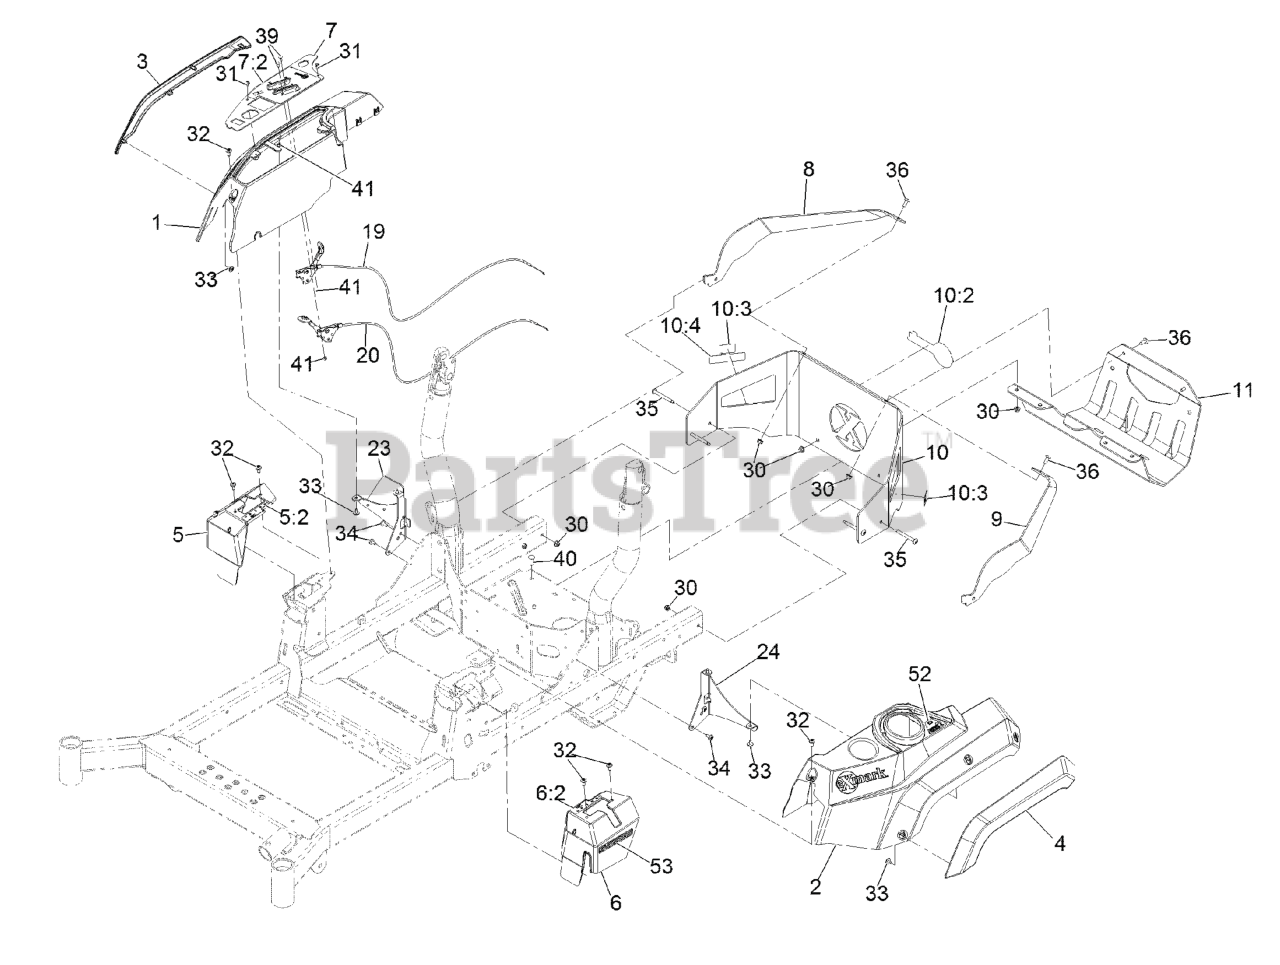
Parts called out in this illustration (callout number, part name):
1	CONSOLE-EXMARK, RH
2	CONSOLE, LH
3	FENDER-RH
4	FENDER-LH
5	COVER-CONTROL, MOTION (RH
5:2	Decal-Control, Motion (RH)
6	COVER-CONTROL, MOTION (LH
6:2	Decal-Control, Motion (LH)
7	CTRL PANEL ASM W/DECAL
7:2	DECAL-CONTROL PANEL
8	SUPPORT-UPPER, RH
9	SUPPORT-UPPER, LH
10	REAR GUARD ASM
10:2	DECAL-EXMARK LOGO
10:3	DECAL-WARNING
10:4	DECAL-ARRESTOR, SPARK
11	GUARD-MUFFLER
19	CABLE-CONTROL, CHOKE
20	CABLE-CONTROL, THROTTLE
23	SUPPORT-CONSOLE, RH
24	BRACKET-CONSOLE, LH
30	NUT-HF, NI
31	SCREW-HWH
32	SCREW-SHOULDER
33	SCREW-TORX
34	SCREW-TORX
35	SCREW-TORX
36	SCREW-TORX
39	BOLT-CARR
40	SCREW-CARR
41	NUT-LOCK, NI
52	DECAL-FILL, FUEL
53	DECAL-S-SERIES
